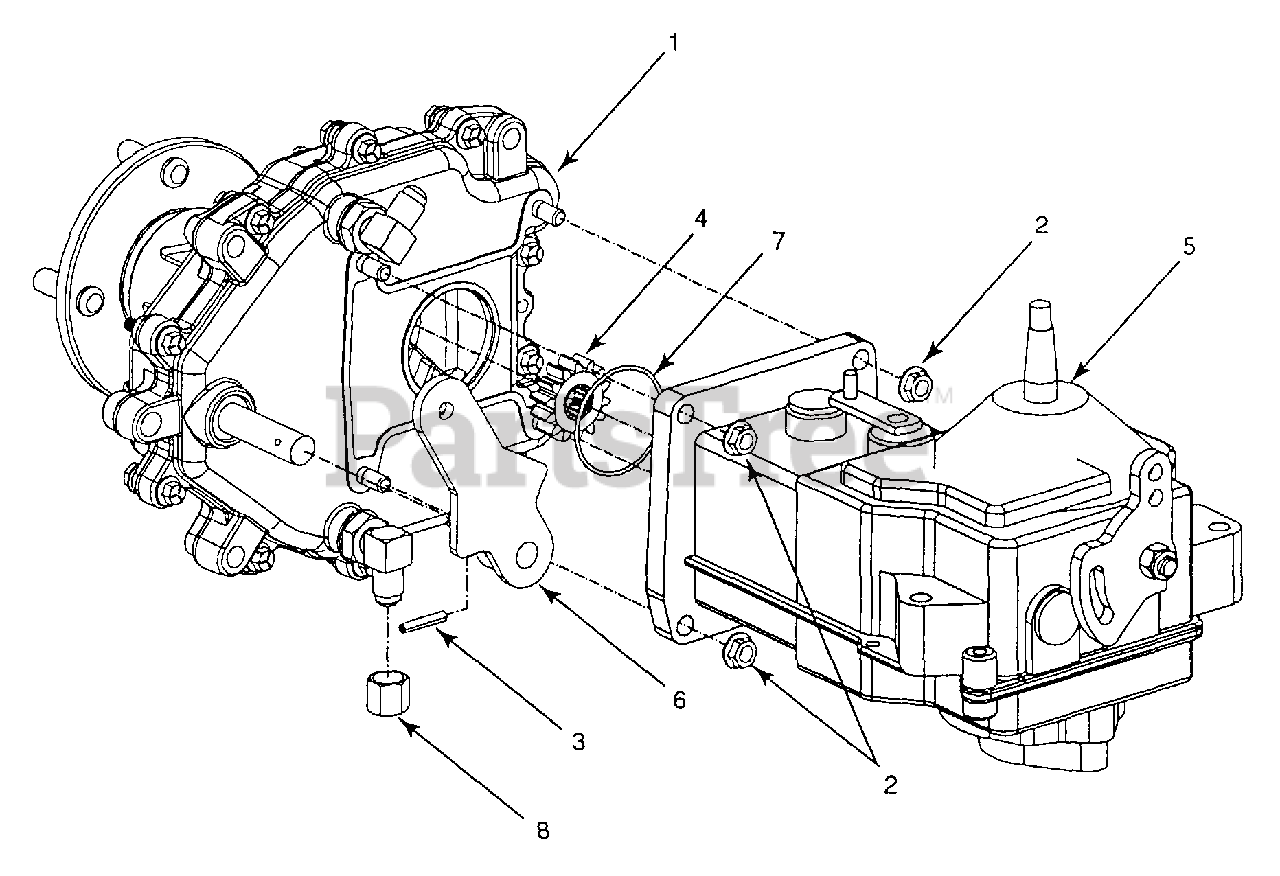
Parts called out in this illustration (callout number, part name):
1	Drive Ass'y, Complete Final
2	Nut, Hex Flange Lock, 5/16-18 GR5
3	Pin, Spirol, 3/16 x 1.0 HD
4	Gear, Spur, 14T
5	Transmission, Hydro: BDR
6	Lever, Park Brake
7	O-Ring, 2.0 Dia
8	Nut, Cap, 3/8
